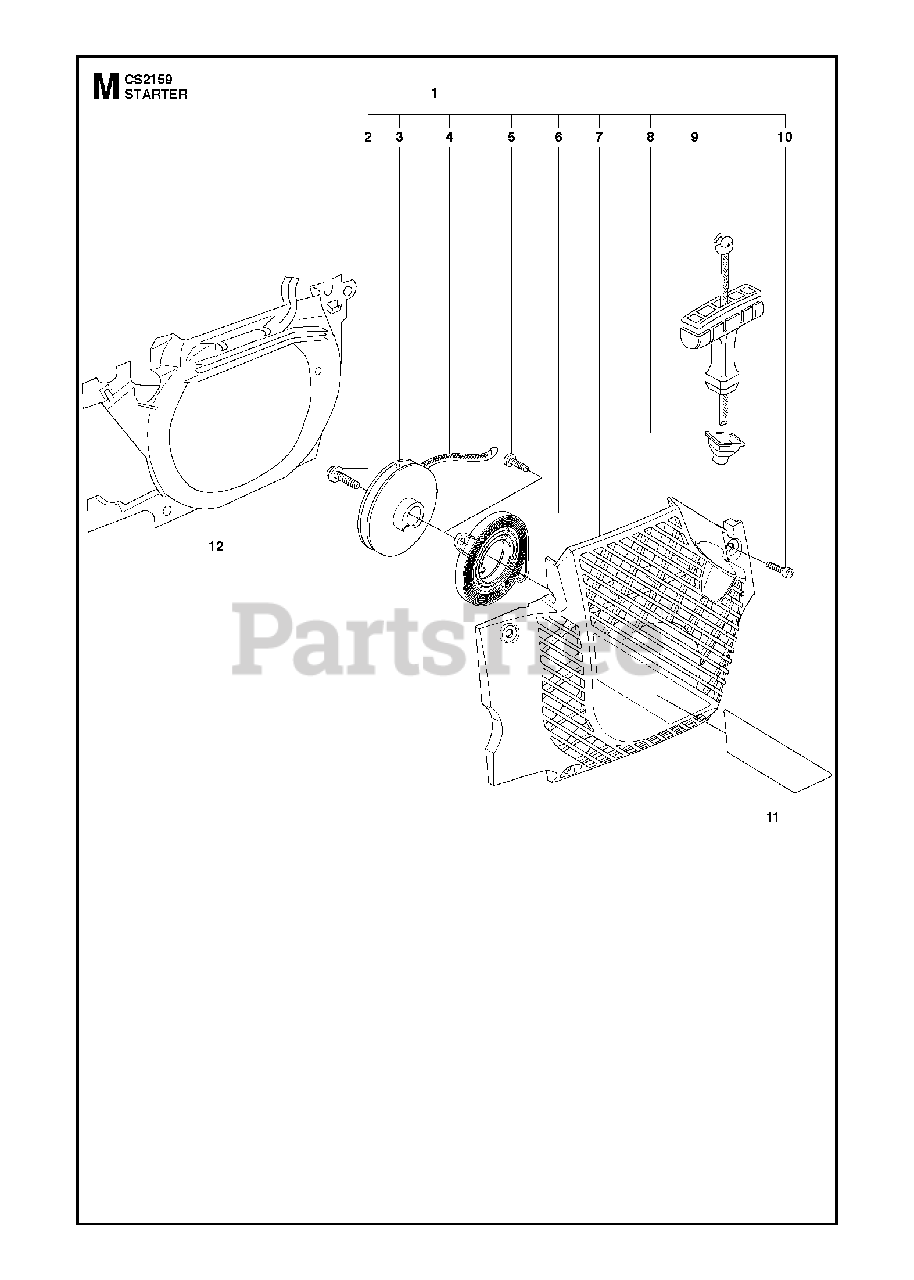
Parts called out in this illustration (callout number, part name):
1	STARTER DEVICE
2	SCREW
3	STARTER PULLEY
4	STARTER ROPE
5	SCREW
6	RETURN SPRING
7	STARTER HOUSING
8	SLEEVE
9	STARTER HANDLE
10	SCREW
11	LABEL
12	AIR CONDUCTOR
